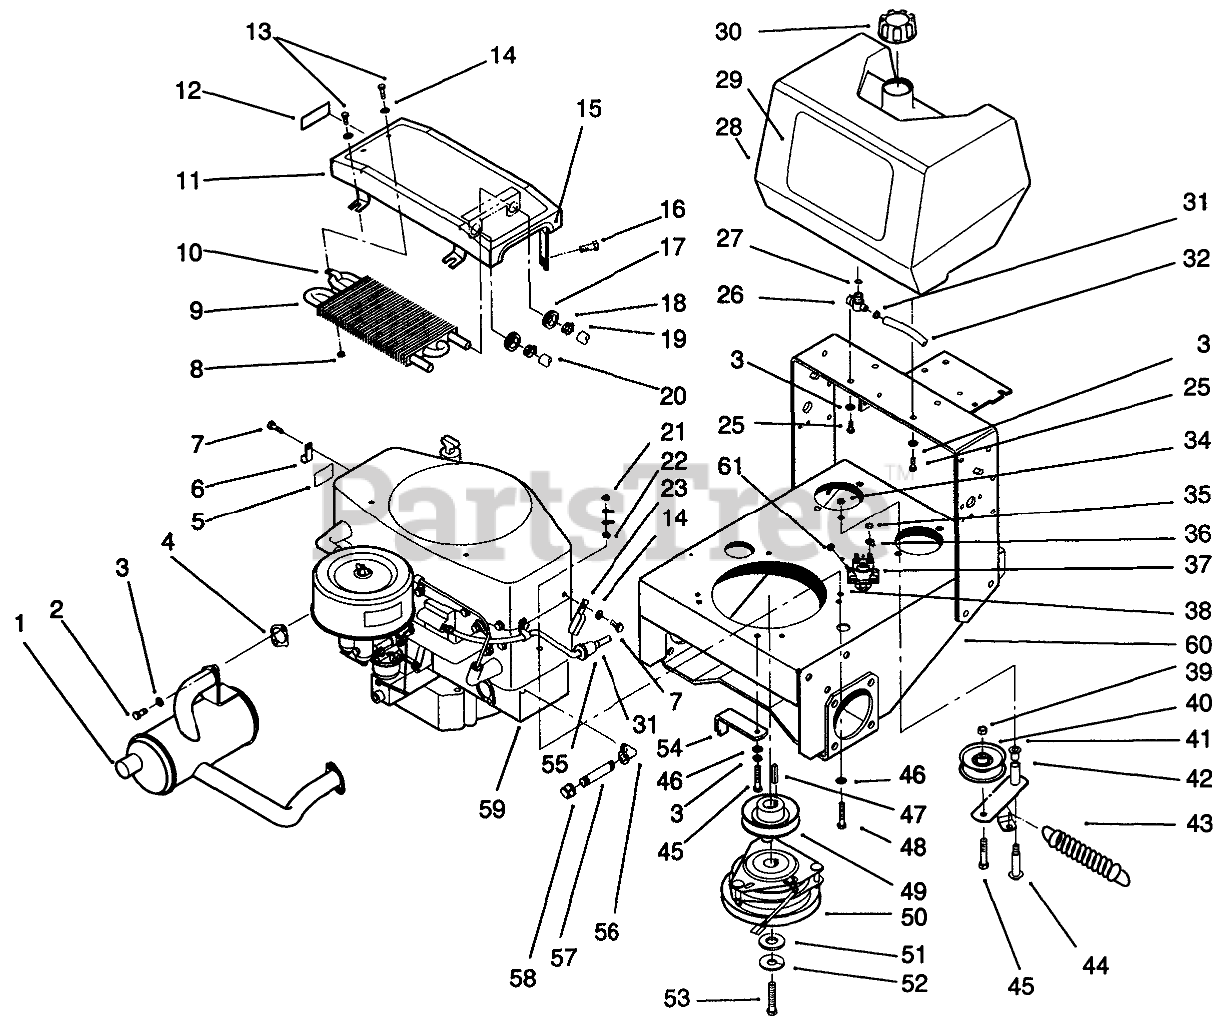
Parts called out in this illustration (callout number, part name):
1	MUFFLER
2	SCREW-HSH
3	WASHER-LOCK
4	EXHAUST GASKET F/W ENG.
5	DECAL-SURFACE, HOT
7	Screw-(Incl w/Engine)
8	NUT-LOCK, NI
9	Cooler-Oil
10	CLAMP-R
11	COOLER MOUNT WA 18 HPB
12	DECAL-FUEL SHUT OFF
13	SCREW-HH
14	WASHER-FLAT
15	TRIM-MOUNT, COOLER
16	Screw-(Incl. w/Engine)
17	GROMMET
18	CLAMP-HOSE
19	HYDRAULIC HOSE ASM
20	HYDRAULIC HOSE ASM
21	NUT-KEPS
22	NUT-LOCK, CONE
23	CLAMP-R, DOUBLE
25	SCREW-HH
26	VALVE-FUEL
27	O-RING
28	FUEL TANK
29	Decal-Toro
30	GAS CAP ASM
31	CLAMP-HOSE
32	GAS HOSE
34	NUT-LOCK
35	NUT-KEPS
36	WIRE-SOLENOID/STARTER
37	Solenoid
38	Screw-Hex. Hd.
39	Nut
40	PULLEY
41	BUSHING-FLANGE
42	Idler Assembly
43	SPRING
44	BOLT-WHEEL
45	SCREW-HH
46	WASHER-PLAIN
47	KEY-SQUARE
48	SCREW-HH
49	Pulley
50	CLUTCH/BRAKE
51	Washer-Clutch
52	WASHER-LOCK
53	SCREW-HH
54	Retainer-Clutch
55	Filter-Fuel (Incl w/Engine)
56	ELBOW-STREET, 90 DEG
57	NIPPLE
58	CAP-PIPE
59	Engine 18Hp. Kohler
60	Frame
61	NUT-KEPS
